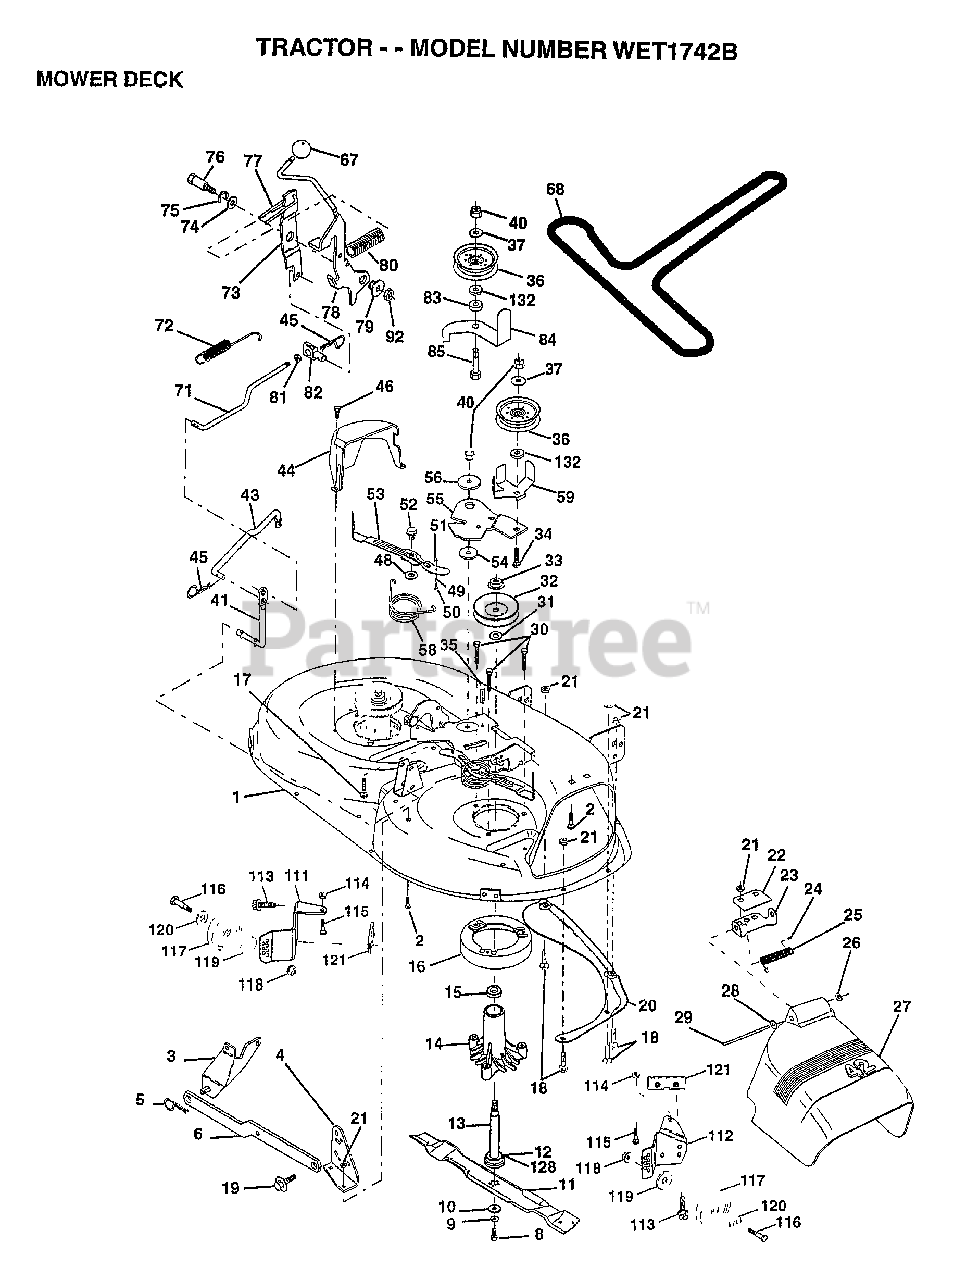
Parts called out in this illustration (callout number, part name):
1	DECK.WELD.42.
2	BOLT
3	BRKT ASM SWAY BAR
4	BRKT DECK SW BAR
8	BLADE BOLT
10	WASHER.HARD.BLADE
11	"BLADE.42"" HIPERF"
12	BEARING.BALL
14	HSG ASM MANDREL
15	BEARING
16	STRIPPER RND MWR
17	BOLT RDHD 3/8-16
18	BOLT
19	BOLT SHD 5/16-18
22	STIFFENER BRKT
23	DEFLECTOR BRKT
24	CAP-SLEEVE LT
25	SPRING TORSION
26	NUT PUSH M
27	DEFLECTOR.SHIELD
28	WASHER
29	HINGE ROD
31	WASHER
32	PULLEY.MANDREL.42
34	BOLT
35	XMAS TREE FASTNER
36	FLAT IDLER PULLEY
37	WASHER
41	PIVOT ROD
43	ROD CLUTCH W/NIBS
44	GUARD MAND LH BLK
45	RETAINER M
46	SCREW.1/4-20X5/8
48	HARD SMALL WASHER
49	ROLLER ASM-CAM
50	SHOULDER BOLT
51	LOCKNUT
52	BOLT.SHLD.5/16-18
54	HARDENED WASHER
55	ARM-IDLER
56	SPACER RETAINER
58	SPRING TORSN BRAK
59	GUARD IDLER TUV
67	KNOB T(3/8 HOLE)
68	BELT.V.T-PATH
71	ROD CLUTCH 38/42
72	RETURN SPRING
73	CLUTCH ARM SECOND
74	WASHER
75	RING
76	SHOULDER BOLT
77	SPRING KEEPER
78	LEVER ASM-CLUTCH
79	BUSHING
80	SPRING.CLUTCH.MWR
81	NUT
82	TRUNION ADJ
83	WASHER
84	"KEEPER-BELT,FIXED"
85	BOLT RDHD 3/8-16
92	NUT
111	BRACKET.GWHL.LH.
112	BRACKET.GWHL.RH.
113	SCREW
116	BOLT M
117	WHEEL.GAGE.BLK.PL
118	LOCKNUT
119	WASHER
120	WASHER
121	BRACKET.EXTRD.GWL
128	WASHER.FELT.
132	WASHER GT
